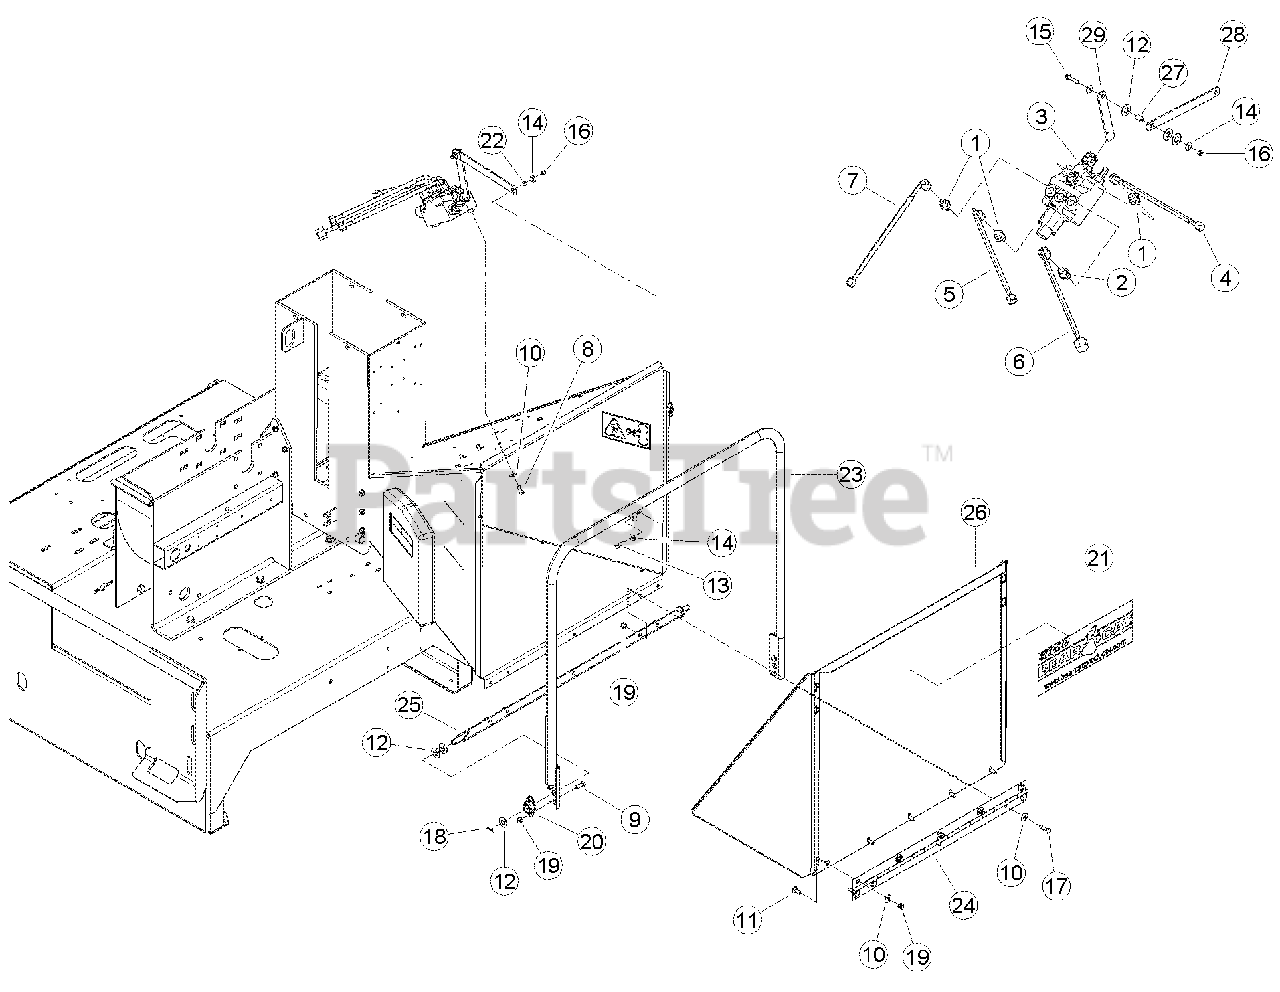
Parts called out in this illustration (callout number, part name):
1	ADAPTER, -8 MORING / -8 MJIC
2	ADAPTER, -10 MORING / -8 MJIC
3	VALVE, 4 POSITION W/DETENTS
4	HOSE ASSY, -8 FMJIC / -8 FMJIC90SW X 37
5	HOSE ASSY, -8 FMJIC / -8 FMJIC90SW X 35
6	HOSE ASSY,-10 FMJIC / -8 FMJIC90SW X 53
7	HOSE ASSY, -10 FMJIC / -8 FMJIC90SW X 82
8	BOLT, 3/8 X 3/4 HEX HD GR5 ZP
9	BOLT, 3/8 X 1 HEX HD GR5 ZP
10	WASHER, 3/8 FLAT ZP
11	BOLT, 3/8 X 1 CRG GR5 NC ZP
12	WASHER, 5/8 SAE FLAT ZP
13	BOLT, 5/16 X 1 HEX HD GR5 NC ZP
14	WASHER, 5/16 FLAT ZP
15	BOLT, 5/16 X 1-1/2 HEX HD GR5 ZP
16	NUT, 5/16 NE NYLOCK ZP
17	BOLT, 3/8 X 1-1/4 HEX HD GR5 ZP
18	PIN, 1/8 X 1.00 COTTER ZP
19	NUT, 3/8 NE NYLOCK ZP
20	BEARING, SIDE FLANGE MOUNT 5/8"
21	DECAL, BEARCAT WEB
22	SPACER, IDLER PIVOT
23	WELDMENT, CONTROL ARM
24	HINGE, EXTENSION TRAY
25	WELDMENT, CONTROL PIVOT
26	WLDMENT, CHUTE EXTENSION TRAY
27	SPACER, .50 X .775
28	LEVER, VALVE CONTROL
29	LINK, VALVE CONTROL
